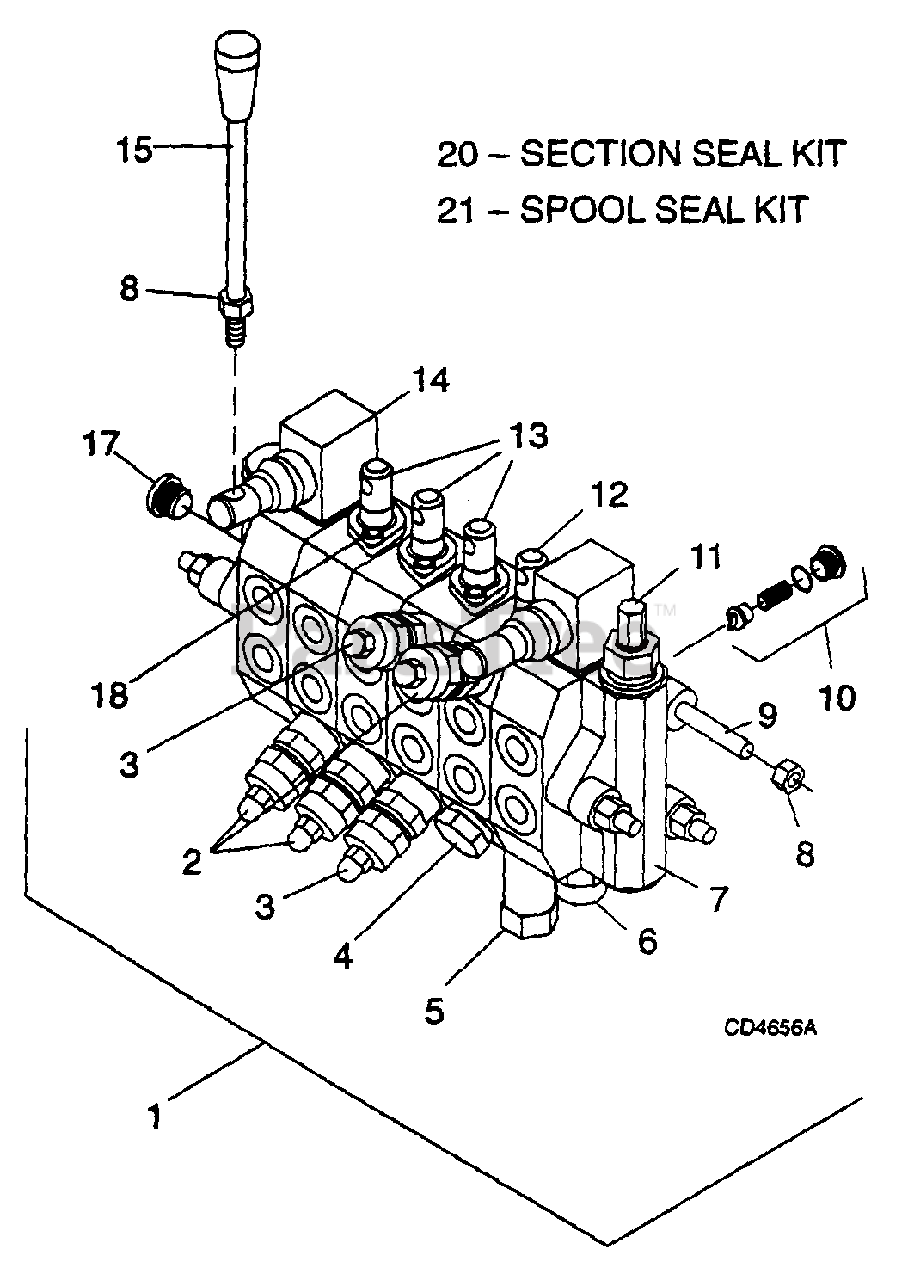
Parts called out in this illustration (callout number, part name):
2	Shock/dampening valve 2500 psi
3	Port relief valve/anit-cav 2100 psi
4	Plug, Port relief cavity
5	Spool position control assembly
6	Spool position control assembly
7	Valve inlet section
8	8mm x 1.25P Hex nut
9	8mm x 1.25P x 276mm Hex head cap screw
10	Check valve assembly
11	Relief valve assembly
12	Boom section with relief
13	Valve spool section without relief
14	Control assembly - Stabilizer
15	Control handle - Stabilizer
17	Plug, 3/4 SAE M with O-ring
18	5mm x .8P x 12mm Hex head cap screw
